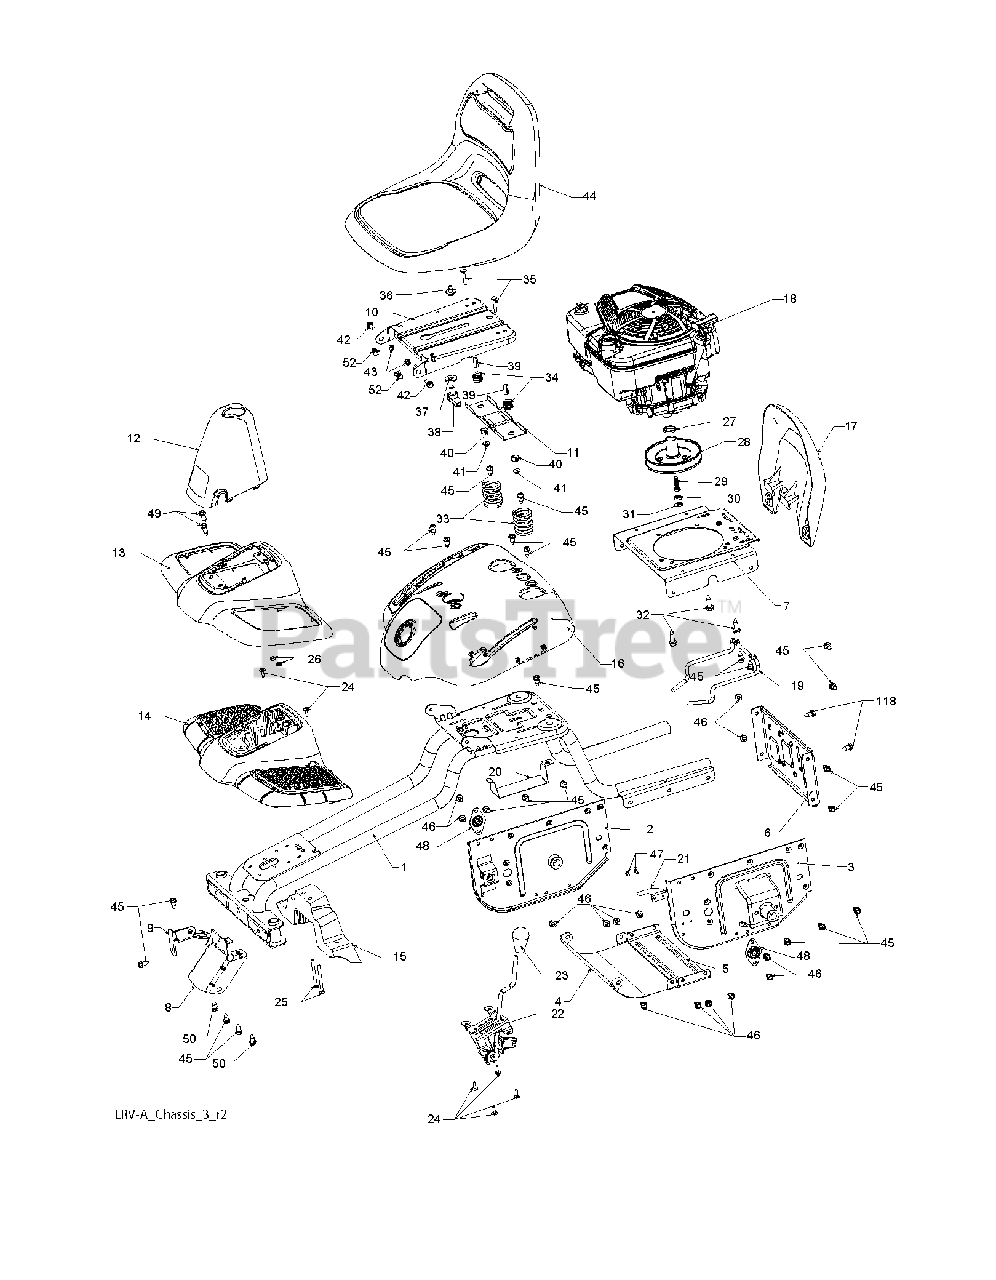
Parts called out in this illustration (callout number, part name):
1	CHASSIS.WLD.26".LRV
2	RP SUPPORT, AXLE RH
3	SUPPORT, AXEL LH
4	SHIELD, TRANSAXLE FRONT
5	STRAP.CROSS.FRICTION.DRIVE
6	COVER, FRICTION DRIVE
7	PLATE, ENGINE
8	BRACKET, CHASSIS FRONT
9	BRACKET, STEERING SUPPORT
10	PAN.ASM.SEAT.1SLOT
11	BRKT.MNTNG.SWITCH.SEAT.BLACK
13	FOOTREST.AESTHETIC.WE.GRN.LRV
14	STRUCTURE, FOOT REST
15	SUPPORT, FOOT REST
16	FENDER.CNTRL.PNL.WE.GRN.LRV
17	GUARD.ENGINE.LRV
19	KEEPER, BELT
20	BRACKET, BATTERY LRV
21	LEVER, SWITCH
22	CABLE.ASM.CLUTCH.W/BRACKET
23	KNOB.OVAL.CUSTOM.BLACK
24	SCREW.#10 X 0.750.BOS (2 2)
25	BOLT.CARRIAGE
26	NUT
27	SPACER.ENGINE.B&S.LRVA
28	DISC, FRICTION ASM
29	BOLT, SCKT HD 3/8-24 X 1 .25
30	BEARING.BALL.689ZZ
31	SPACER.NEUTRAL
33	SPRING COMPRESSION
35	BOLT.ROUND.HEAD.SQUARE.NECK
36	BOLT,SHOULD
38	KNOB.SEAT.ADJ.WINGNUT
39	SPACER SPLIT 28X.96
41	NUT T
42	BOLT.SHOULDER.5/16-18
43	NUT.71038.31-18.HEX.NYLOCK
44	SEAT.SUBASY.OPP.WEEDEATER.LRVA
45	SCREW
46	SCREW LT
48	BEARING FLANGE BALL
49	SCREW 5/16-18X1
50	BOLT.SHOULDER.5/16-18X
52	PUSH CLIP
118	SHOULDER BOLT 5/16-18TT
